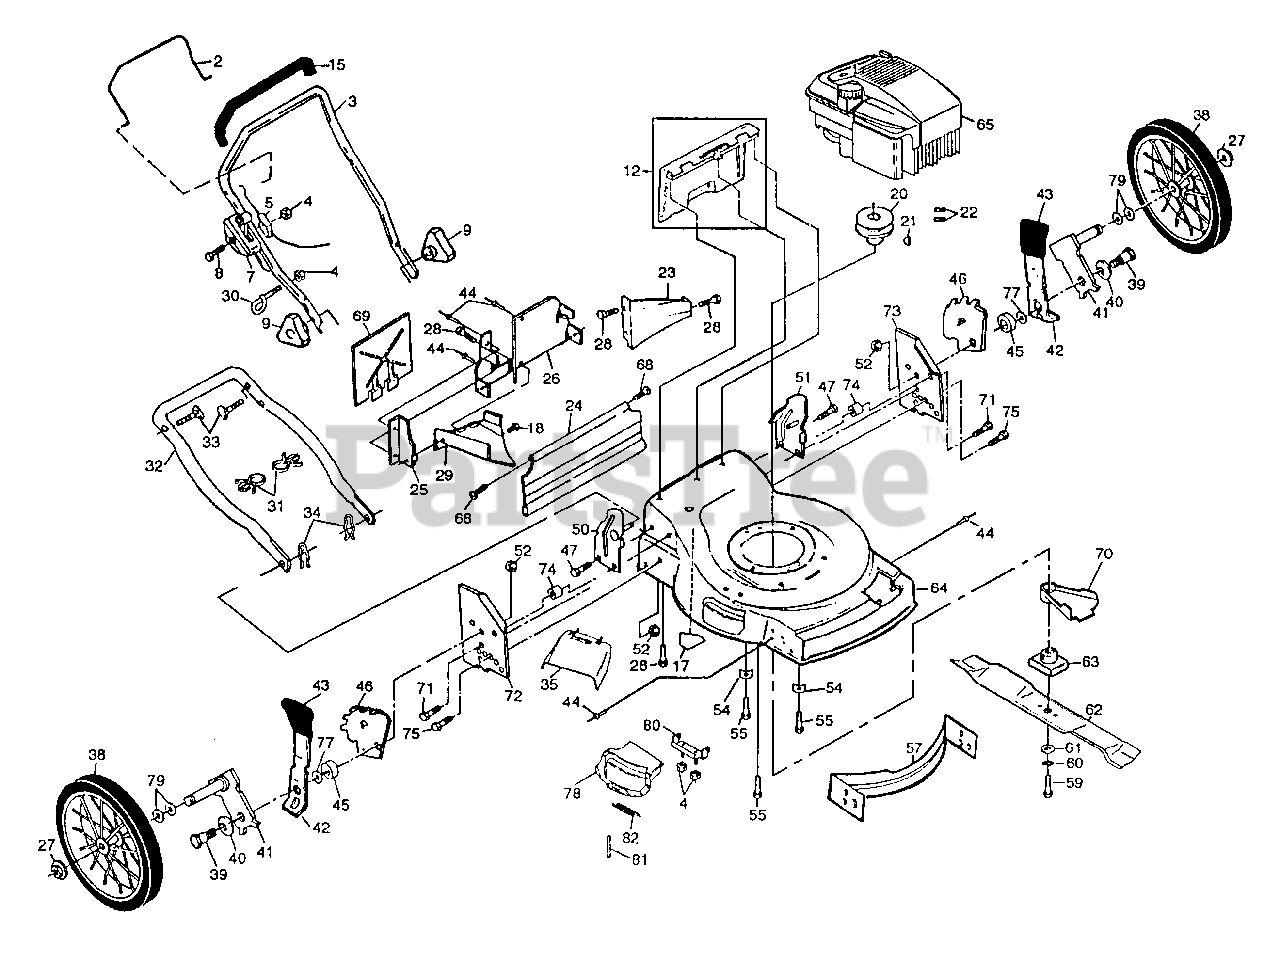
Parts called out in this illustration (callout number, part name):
2	Control Bar (AYP part number)
3	Upper Handle
4	Locknut
5	Engine Zone Control Cable
7	Throttle Control
8	Hex Washer Head Screw 1/4-20 x 2-1/8
9	Handle Knob (AYP part number)
12	Rear Door Kit
15	Handle Grip
17	Danger Decal
18	Screw #10
20	Engine Pulley
21	Hi Pro Key #505
22	Set Screw 1/4-20 x 5/16 (AYP part number)
23	Baffle, Rear (AYP part number)
24	Rear Skirt
25	Side Baffle (AYP part number)
26	Back Plate (AYP part number)
27	Flanged Locknut
28	Screw Hex Head 1/4-20 x 1/2
29	Discharge Baffle
30	Rope Guide (AYP part number)
31	Cable Clip
32	Lower Handle
33	Handle Bolt (AYP part number)
34	Hairpin Cotter
35	Clip-on Discharge Deflector
38	Wheel & Tire Assembly
39	Shoulder Bolt
40	Spring Washer
41	Axle Arm
42	Selector Spring
43	Selector Knob
44	Pop Rivet
45	Spacer
46	Wheel Adjusting Bracket
47	Self-tapping Screw 5/16-18 x 3/4
50	Handle Bracket (Right)
51	Handle Bracket (Left)
52	Locknut 3/8-16 (AYP part number)
54	Engine Washer (AYP part number)
55	Hex Head Thread Rolling Screw 3/8-16 x 1-1/8
57	Front Baffle (AYP part number)
59	Hex Head Machine Screw 3/8-24 x 1-3/8 Gr. 8
60	Helical Lock Washer (AYP part number)
61	Hardened Washer
62	Blade 22"
63	Blade Adapter
64	Lawn Mower Housing Kit
65	Engine (See Breakdown)
68	Hinge Screw
69	Mulcher Plate (AYP part number)
70	Debris Shield (AYP part number)
71	Thread Cutting Screw 5/16 - 18 x 1-1/2
72	Support Bracket (RH) (AYP part number)
73	Support Bracket (LH) (AYP part number)
74	Spacer
75	Bolt
77	Flat Washer
78	Combi-cut Door
79	Wave Washer
80	Hinge Bracket
81	Rod
82	Hinge Spring
